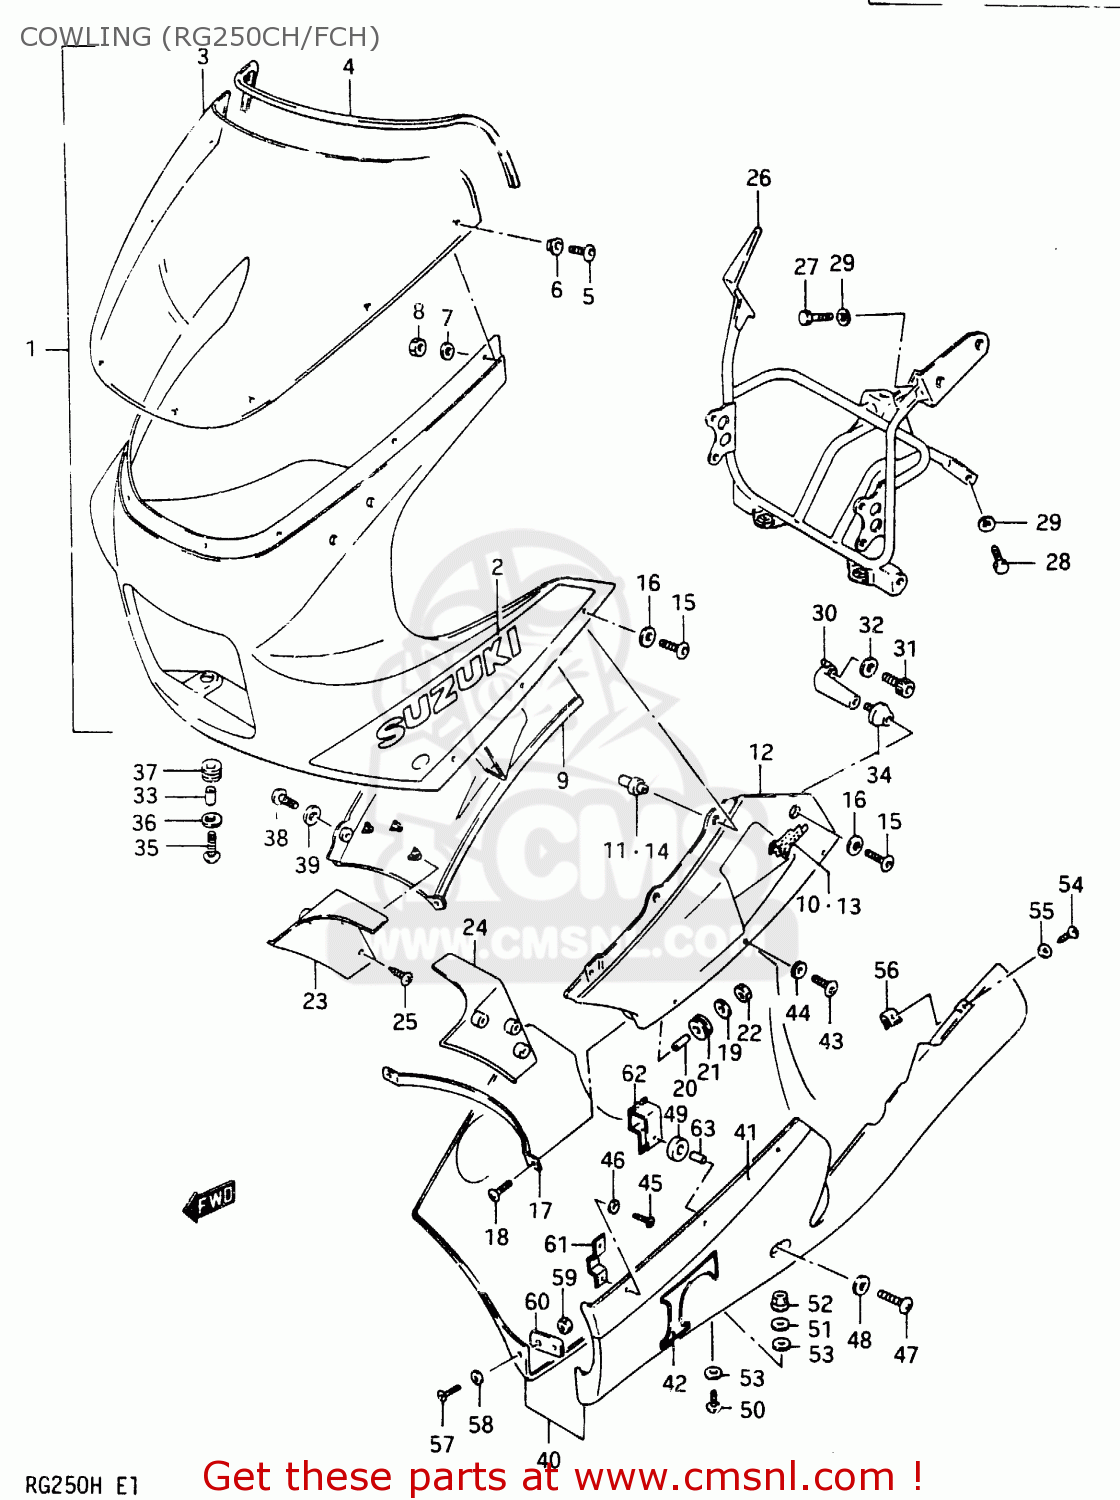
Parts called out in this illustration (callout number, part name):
1	COWLING ASSY (BLUE)
2	TAPE SET
3	WINDOW
4	MOLDING
5	SCREW(5X14)
6	CUSHION
7	WASHER,5MM
8	NUT 8MM
9	COVER, RH (WHITE/RED)
10	EMBLEM
11	NUT,COWLING COVER
12	COVER, LH (WHITE/RED)
13	EMBLEM
14	NUT,COWLING COVER
15	SCREW(6X20)
16	WASHER(6.5X16X1.2)
17	PANEL, COWLING LOWER (WHITE)
18	SCREW
19	WASHER (6.5X20X1.2)
20	SPACER (6.8X10X10)
21	CUSHION
22	NUT 6MM
23	GUIDE PLATE, RH
24	GUIDE PLATE, LH
25	SCREW
26	BRACE, COWLING
27	BOLT
28	BOLT
29	WASHER,LOCK,8.
30	SPACER, COWLING LOWER
31	BOLT
32	WASHER
33	SPACER(6.5X11.5X12)
34	CUSHION,COWLING
35	SCREW(6X20)
36	WASHER
37	CUSHION
38	SCREW(6X30)
39	WASHER(6.5X16X1.2)
40	COWLING ASSY, UNDER (WHITE/BLUE)
41	TAPE SET
42	EMBLEM
43	SCREW(6X12)
44	WASHER(6.5X16X1.2)
45	SCREW
46	WASHER
47	SCREW
48	WASHER(6.5X16X1.2)
49	CUSHION
50	SCREW
51	WASHER
52	NUT
53	WASHER
54	SCREW
55	WASHER
56	NUT
57	SCREW
58	WASHER
59	NUT 4MM
60	BRACKET
61	BRACKET
62	BRACKET
